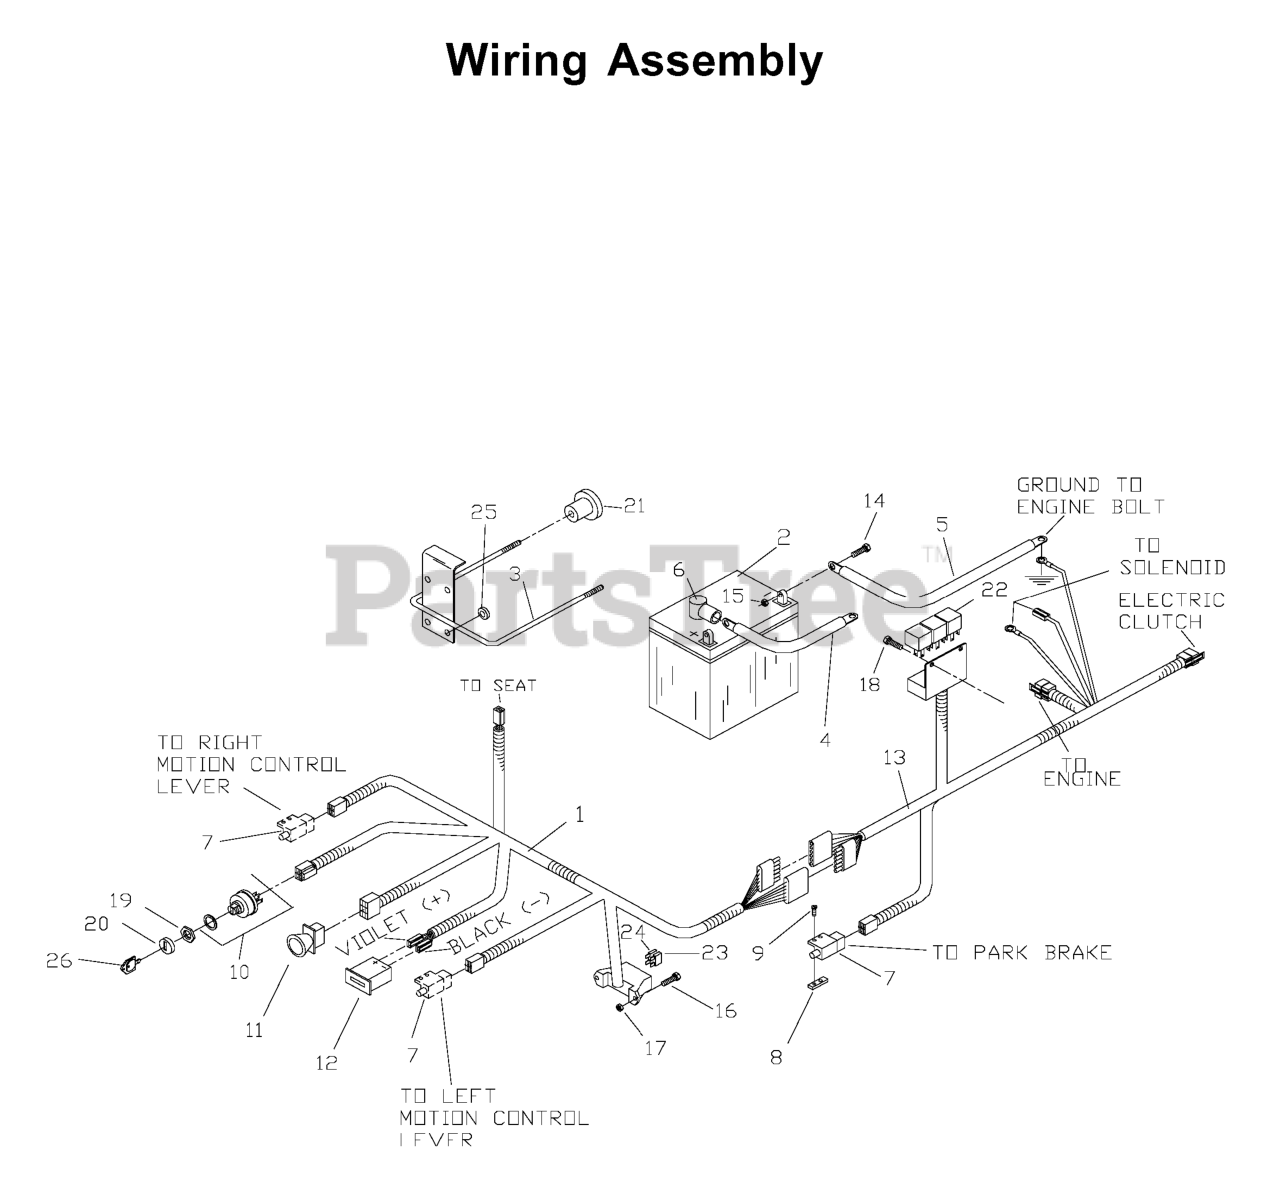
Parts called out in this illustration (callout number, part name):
1	CONSOLE HARNESS
2	BATTERY WET NOT SELLABLE
3	BATTERY HOLD DOWN
4	POST.CABLE LONG
5	CABLE-NEGATIVE
7	SWITCH, INTERLOCK
8	TAPPED PLATE
9	SCREW #10-24 X 5/8
10	IGNITION SWITCH KIT
11	RP.SWITCH, BLADE
12	HOUR METER
13	FRAMES HARNESS
14	HCS 5/16C X 3/4
15	NUT 5/16C CENTERLOCK
16	SCREW, #1--24 X 1/2 SLOTTED
17	NUT 10-24 NYLOC
18	SCREW #10 X 1/2 SELF TAPPING
19	DNO IGNITION NUT
20	CAP IGNITION NUT
23	FUSE, 7.5 AMP 32 VOLT ATO
24	FUSE, 20 AMP 32 VOLT ATO
25	GROMMET, BUMPER
26	KEY-PADDED
